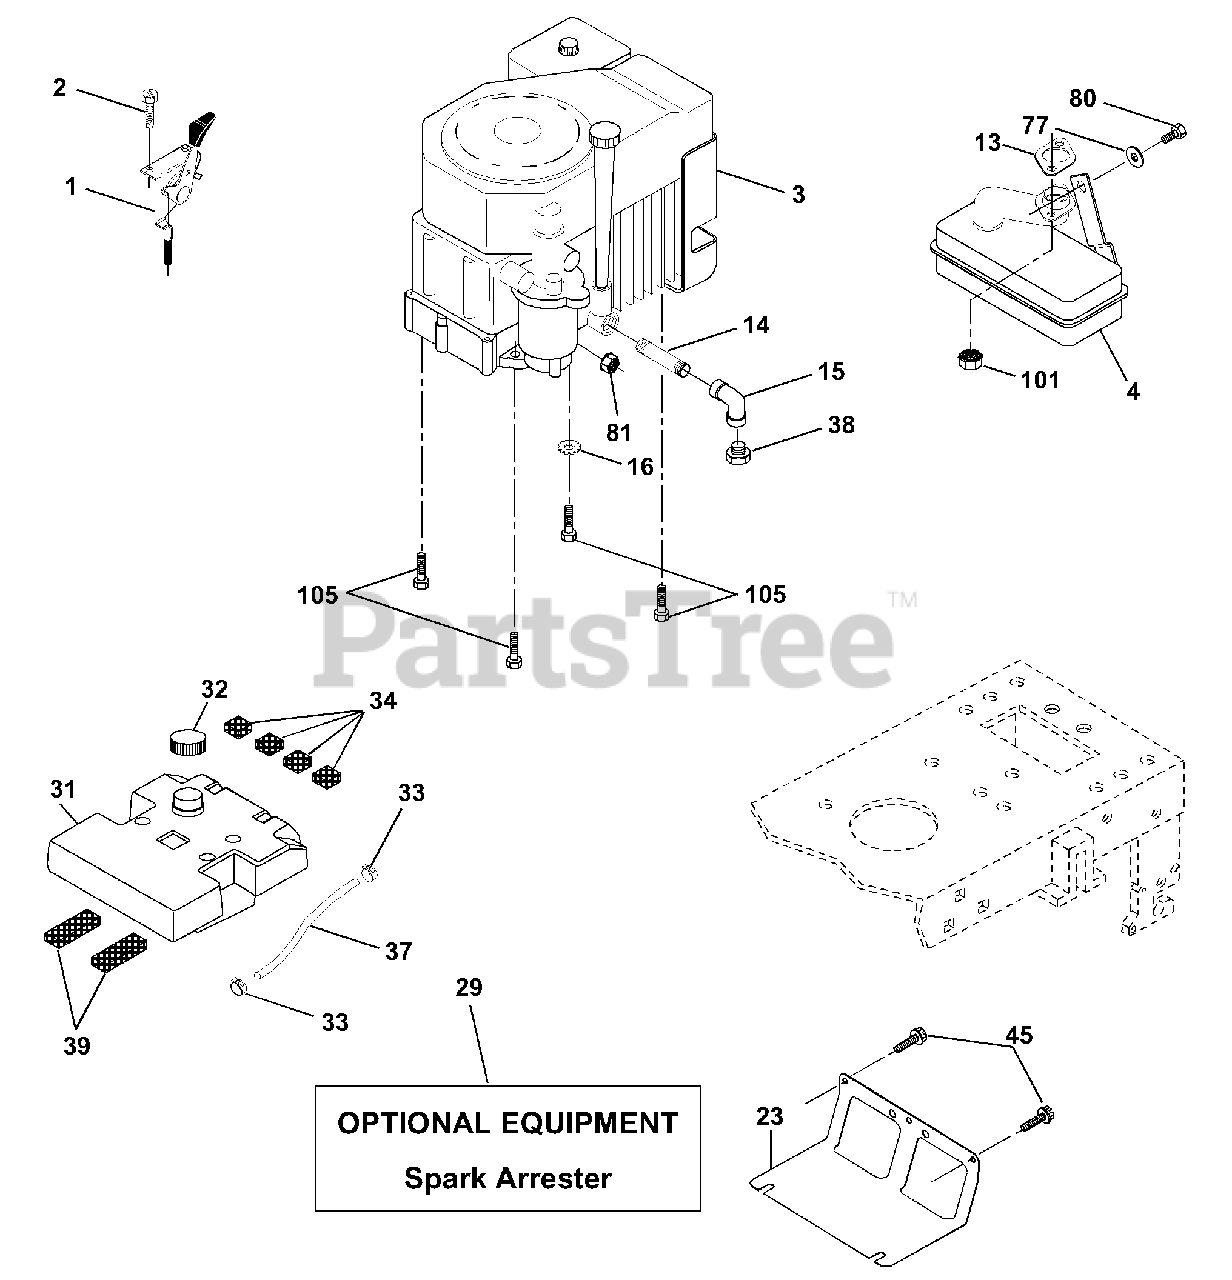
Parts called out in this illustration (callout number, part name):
1	Control Th/ch 27. LH. Flag Dom.
2	Screw Hex Thd Cut 1/4-20 x 5/8 T
4	Muffler Kohler Single w/Port
13	Gasket Kohler CV13-CV16.5
14	Nipple Pipe 3/8 Npt X 3-1/2
15	Elbow Std 90 Degree 3/8-18 Npt
16	Washer Lock Ext Tooth 3/8
23	Shield BRN/DBR Guard
29	Kit Spark Arrestor (Flat Scrn)
31	Tank Fuel 3.5 STLT W/O Sensor
32	Cap Asm Fuel W/sym Vented
33	Clamp Hose Black
34	Pad Spacer
37	Line Fuel 7.5"
38	Plug Oil Drain
39	Pad Idler 1.75 x .75 x .06
45	Screw 3/8-16 x 3/4
77	Washer 5/16 x 3/4 x 16 Ga.
80	Bolt Hex Hd. 5/16-18unc x 1/2
81	Nut Flange 1/4-20 Starter Nut
101	Nut Flange M8-1.25 Non-LK
105	Screw 3/8-16 x 1
